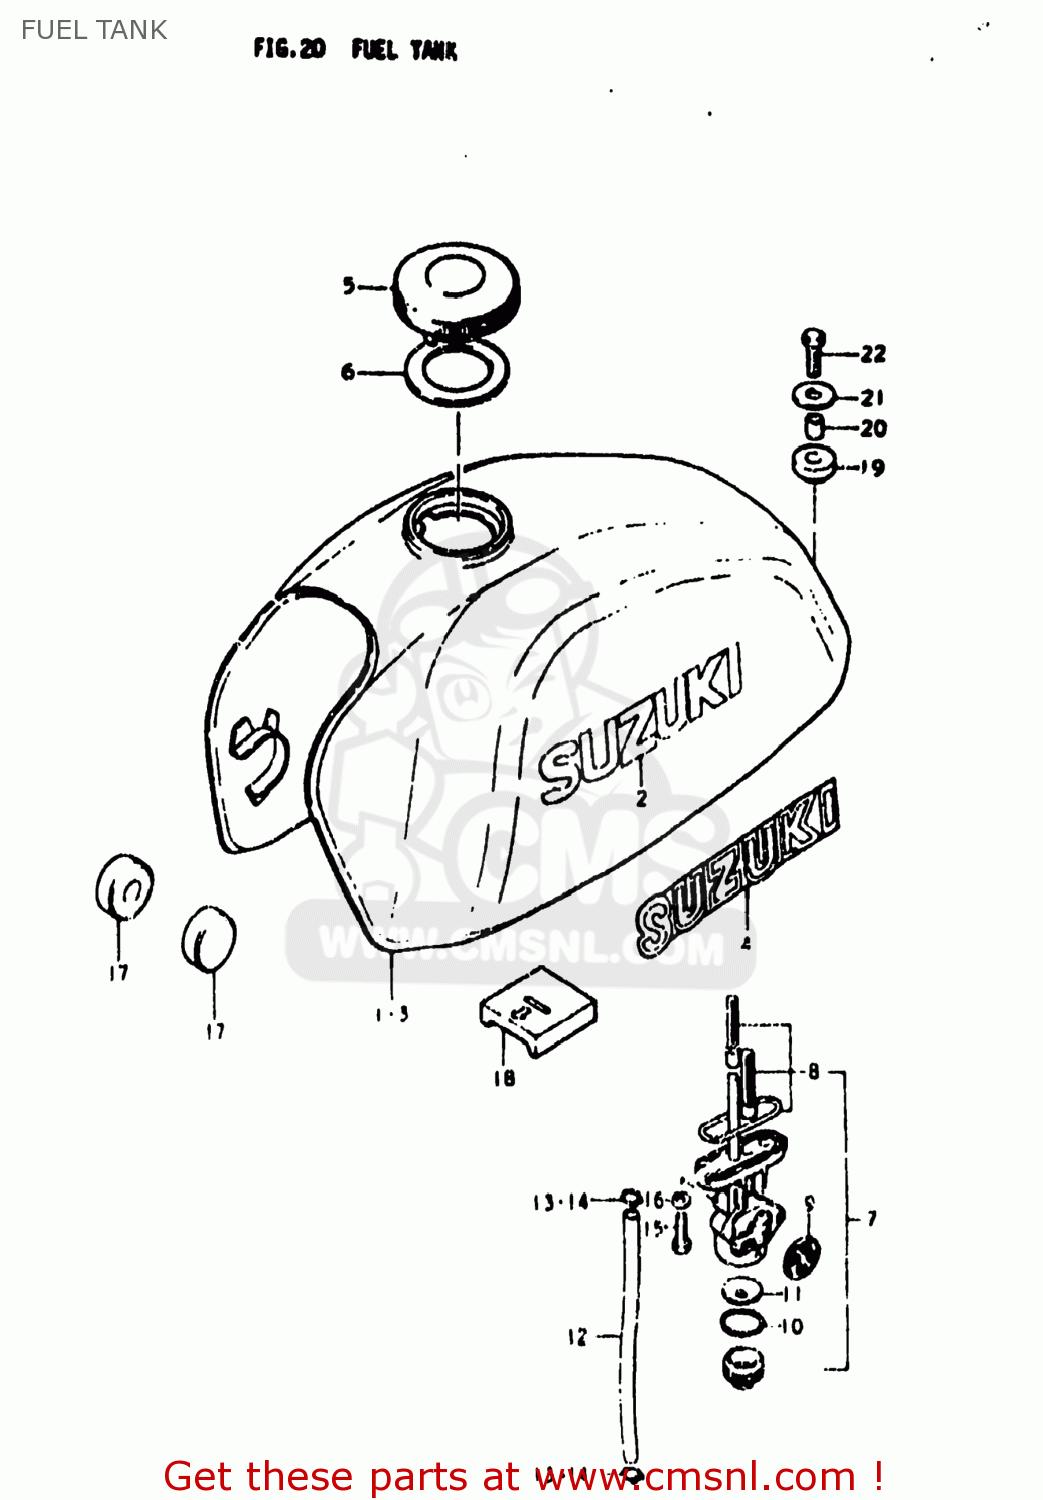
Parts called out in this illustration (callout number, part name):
1	TANK ASSEMBLY,FUEL
2	EMBLEM
3	TANK ASSEMBLY,FUEL
4	EMBLEM
5	CAP,FUEL TANK
6	GASKET (NAS)
7	COCK ASSEMBLY,FUEL
8	FILTER SET,FUEL COCK
9	GASKET,LEVER (NAS)
10	GASKET,FILTER (NAS)
11	NET,STRAINER
12	HOSE
13	CLIP
14	CLIP
15	BOLT L:16
16	GASKET
17	CUSHION
18	CUSHION,FUEL TANK
19	CUSHION
20	SPACER (6.8X10X10)
21	WASHER (6.5X24X1.6)
22	BOLT
